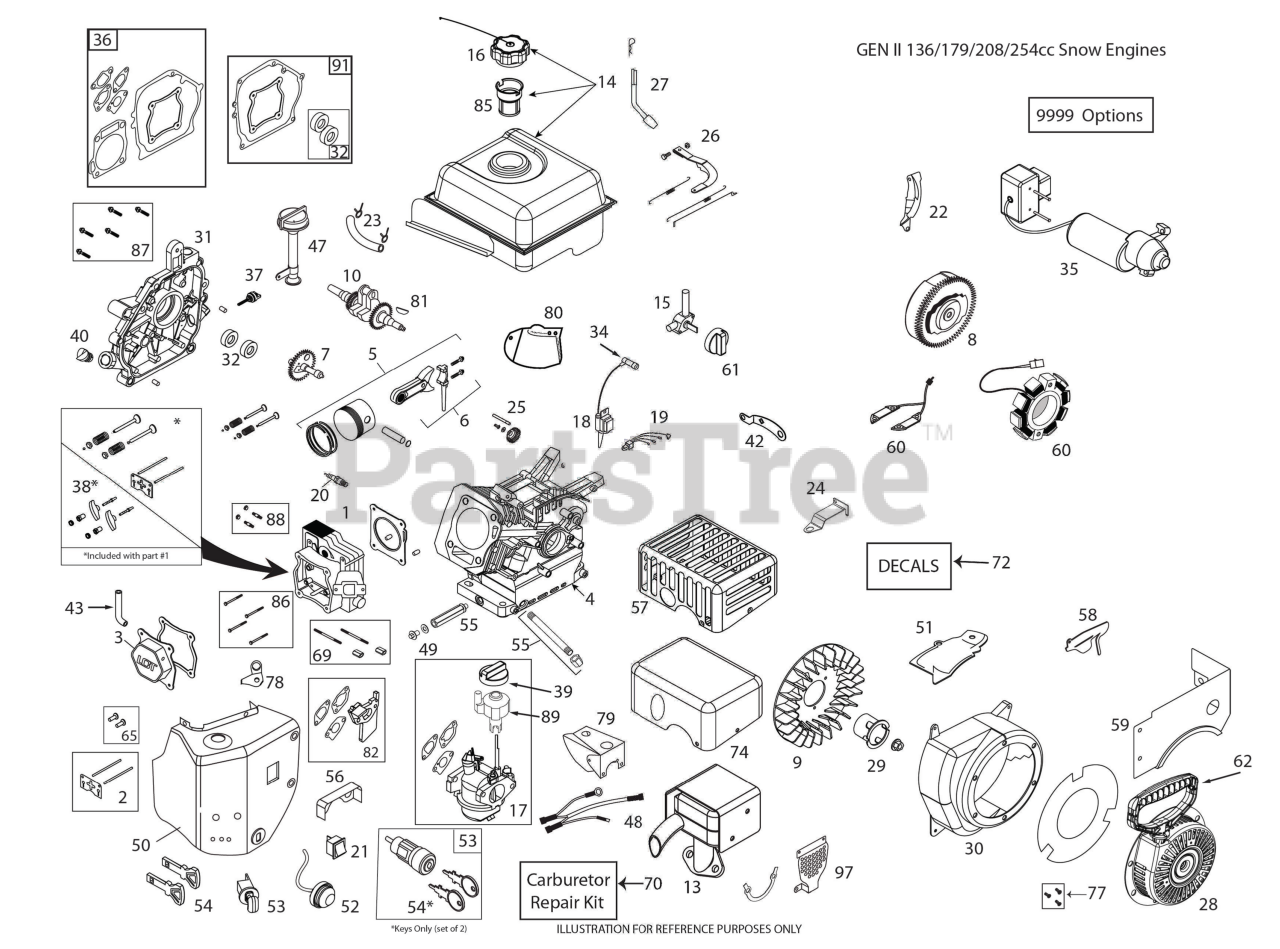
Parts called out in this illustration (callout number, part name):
1	CYLINDR.HEAD.SRV.KIT W/GASKET
2	KIT.PUSH.ROD.SRV(SK208-1001)
3	VALVE COVER ASSEMBLY
4	CYLINDER LCT.208 GEN II SNO
5	KIT.PISTON.SRV(SK208-1400)
6	KIT.CONNECT.ROD.SRV(SK208-1500
7	KIT.CAMSHAFT.208CC.LCT
8	208CC ELEC START FLYWHEEL
8	FLYWHEEL ELECTRIC START W/6 MA
9	FLYWHEEL FAN 420586
10	CRNKSHFT-KYD#14.208CCSKSNO8001
13	ASSY.MUFFLER.GENII.SKSN0201.1
13	MUFFLER KIT LCT SKSN2205.1
14	FUEL.TK.ASSY.GENII.SKSN0311.1
15	FUEL.PETCOCK.SNOW(SKSN4900)
16	FUEL CAP OVERSIZED CLICK STYLE
17	CARBURETTOR L10-1D.W/SP
18	208CC IGN COIL (STD)
18	COIL.ING.CDI.HI TEMP.SKSNO416.
20	SPARK.PLUG(2083810)
21	SWITCH.ON/OFF(SKSN-0403)
22	SHLD.ELEC.START.FLY(SKSN-0605)
22	SHIELD.FLYWHEEL.ELEC.STRT.208C
23	KIT.FUEL.HOSE.208CC.SING/STAGE
24	SPEED.CTRL.BRKT.(SKSN0150)
25	GOVENOR.GEARS ASM(SK2082900)
26	CARBURETTOR GOVERNOR LINK.ASM.
27	KIT.GOVERNOR.CRANK(SK208-3100)
28	RECOIL.STRT.ROUND(BLK) SNOW
29	STRTER.CUP(NON-SLOT)SKSN0601.2
30	BLOWER HOUSING ASSY
31	COVER CRANKCASE.LCT.SK2083605
32	SEAL KIT (2 PCS)
34	SPARK.PLUG.BOOT.SNW,SKSN4691.1
35	ELEC.START.GEN2.SKSN0451.1
36	GASKET.KIT.208CC(SK2084300.1)
37	DIPSTICK SMALL
38	ROCKER ARM KIT
39	CHOKE.KNOW.SNOW(SKSN4500)
40	NON REMOVABLE PLUG
43	TUBE.BREATHER.LCT.208
47	TUBE ASSY HIGH OIL-FILL
48	WIRE.HARNESS.SNOW
48	HARNESS WIRE. W/O OFF/ON SWITC
49	KIT.OIL.DRAIN.PLUG(SK2089911
50	HEATER.BOX.ASY-GEN2
50	BOX HEATER.W/O OFF/ON SWITCH.L
51	SHIELD.CYLINGER.LCT.SKSN0608.1
52	PRIMER.BULB.WITH HOSE (SNOW)
53	SWITH.KEY.ASSEM.SNOW.SINGLE.ST
54	KEY SET(2 KEYS) SKSN0407.1
55	EXTENDED OIL DRAIN TUBE
55	OIL PIPE DRAIN LCT 254
56	SHIELD.VAPOR.SNOW
57	SHIELD.MUFFLER.CE.COMPLIANT
58	GOVERNOR.LINK.SHIELD PLATE
58	SHIELD GOVENOR & CARB - COMPOS
59	FUEL.TNK.SKRT.GENII.SKSN0103.1
60	208CC 60W ALTERNATOR
61	FUEL KNOB-SNOW
62	HANDLE.RECOIL.DELUXE.LCT
65	TAPPET.KIT.LCT.208CC
69	CARB.STUDS & COUPLING KIT.SNOW
70	CARBURETOR.REPAIR KIT.LCT.
70	CARB.REPAIR.KIT.LCT.SK9900.2
72	ARIENS 414 SNOW DECAL KIT
72	KIT.ENGINE.DECAL.208CC.LCT.SK1
74	MUFFLER GUARD.EUR./LCT.SKSN220
74	SHIELD.MUFFLER.CE.COMPLIANT
77	BOLT.KIT.RECOIL.LCT.ALL.ENGINE
79	COVER.CARBURETOR.SNOW
81	KEYS.FLYWHEEL.208/414CC.5PACK
82	SPACER.CARBURETOR.208CC.LCT
85	STRAINER.FUEL.TANK.LCT.208CC
86	BOLT KIT.CYLINDER HEAD.LCT(4)1
86	KIT.BOLT.CYLINDER.HEAD.(4PC)
87	KIT.BOLT.CRANKCASE.COVER.6PC
88	STUD.MUFFLER.KIT.LCT
89	KNOB LCT.SKSN5325.1 SPEED
89	COVER CRANKCASE GASKET
91	CRANKSHAFT GASKET KIT.LCT
91	COVER CRANKCASE GASKET
97	MUFFLE MANIFOLD GUARD.LCT
9999	STARTER SCREW.STARTER SWITCH B
9999	GUARD.MUFFLER.MANIFOLD.LCT
9999	HIGH.ALTITUDE.JET 6,000FT
9999	KIT.BOLT.LCT.SK9990.1
